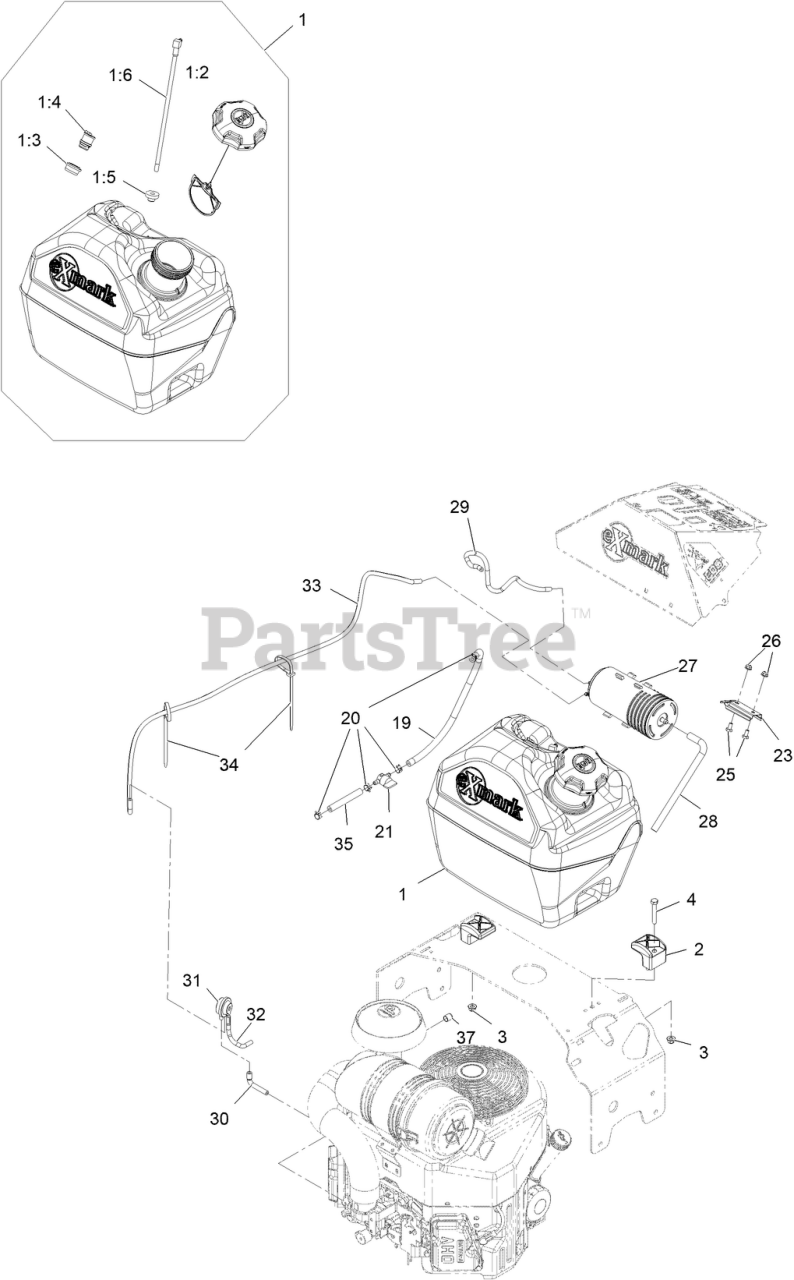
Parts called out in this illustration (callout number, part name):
1	ASM, FUEL TANK 5 GAL
1:2	CAP-FUEL, RATCHETING
1:3	GROMMET
1:4	VALVE-VENT, FUEL
1:5	BUSHING
1:6	FITTING, FUEL W/LINE AND SCREEN
3	NUT-HF, NI
4	SCREW-HH
19	HOSE-FUEL
20	CLAMP-HOSE
21	VALVE-FUEL
23	BRACKET-CANISTER, CARBON
25	SCREW-HH
27	CANISTER-CARBON, 800CC
28	HOSE-VENT, CANISTER
29	HOSE-EMISSIONS
30	HOSE-VENT, FORMED
31	VALVE-CONTROL, VACUUM
32	HOSE-VENT, FORMED
33	HOSE-VENT, FORMED
34	TIE-CABLE
35	HOSE-FUEL
37	PLUG-PORT
